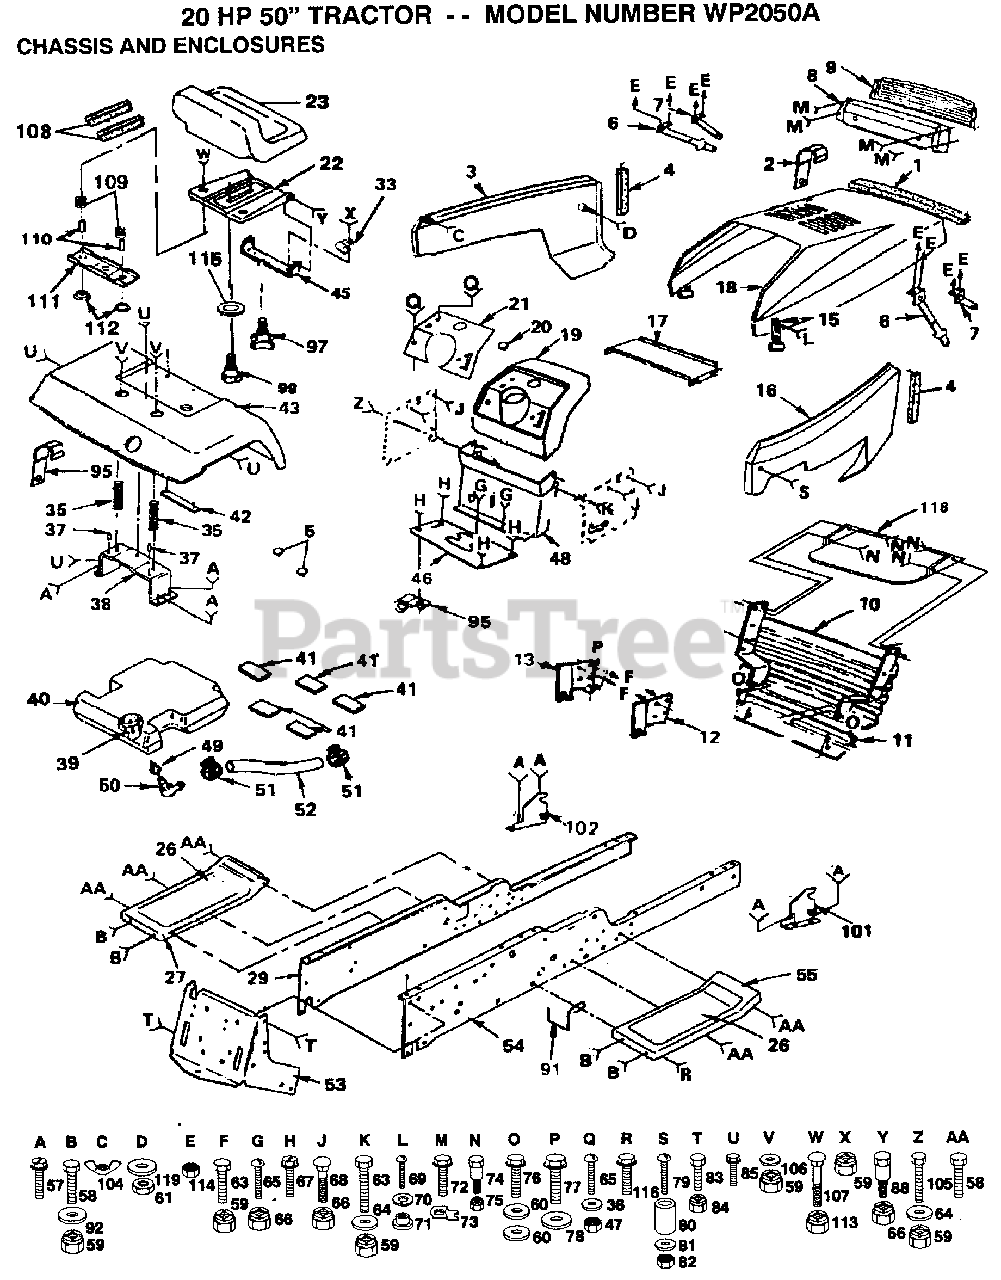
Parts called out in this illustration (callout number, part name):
1	FOAM STRIP T
4	FOAM STRIP T
5	CAP SPRING
9	LENS LT
12	SUPPORT RH YTH
13	SUPPORT LH YTH
15	HOOD LATCH T
16	"PANEL,SIDE RH "
20	PLUG-DASH T
26	FOOTREST PAD
33	CLIP T
35	SPRING COMPRESSIO
36	WASHER
37	NUT-PUSH YT
41	PAD-SPACER LT
43	FENDER
46	CVR GATE SHIFT
48	DASH ASSEMBLY
49	BUSHING OUTLET T
50	FUEL TANK STEM GT
51	HOSE CLAMP
57	SCREW
60	WASHER PM
63	BOLT
64	WASHER
65	SCREW
67	SCREW
68	BOLT
69	SCREW
70	LOCKWASHER
71	WELDNUT
73	"""J"" FASTENER LT"
76	SCREW
77	SCREW
78	WASHER
79	SCREW
80	SPACER LT
81	WASHER
83	BOLT
84	NUT GTV
85	SCREW LT
91	BELT RETAINER GT
92	WASHER
97	"KNOB 1/2"" YT"
99	"BOLT,SHOULDER"
101	SUPPORT RH YTH
102	SUPPORT LH YTH
106	WASHER
108	STRIP FORM
109	SPRING COMPRESSED
110	SPACER SPLIT
111	BRKT SWITCH
112	BUSHING
114	NUT
115	WASHER
116	SCREW GTV
118	"SHIELD,HEAT"
119	WASHER
